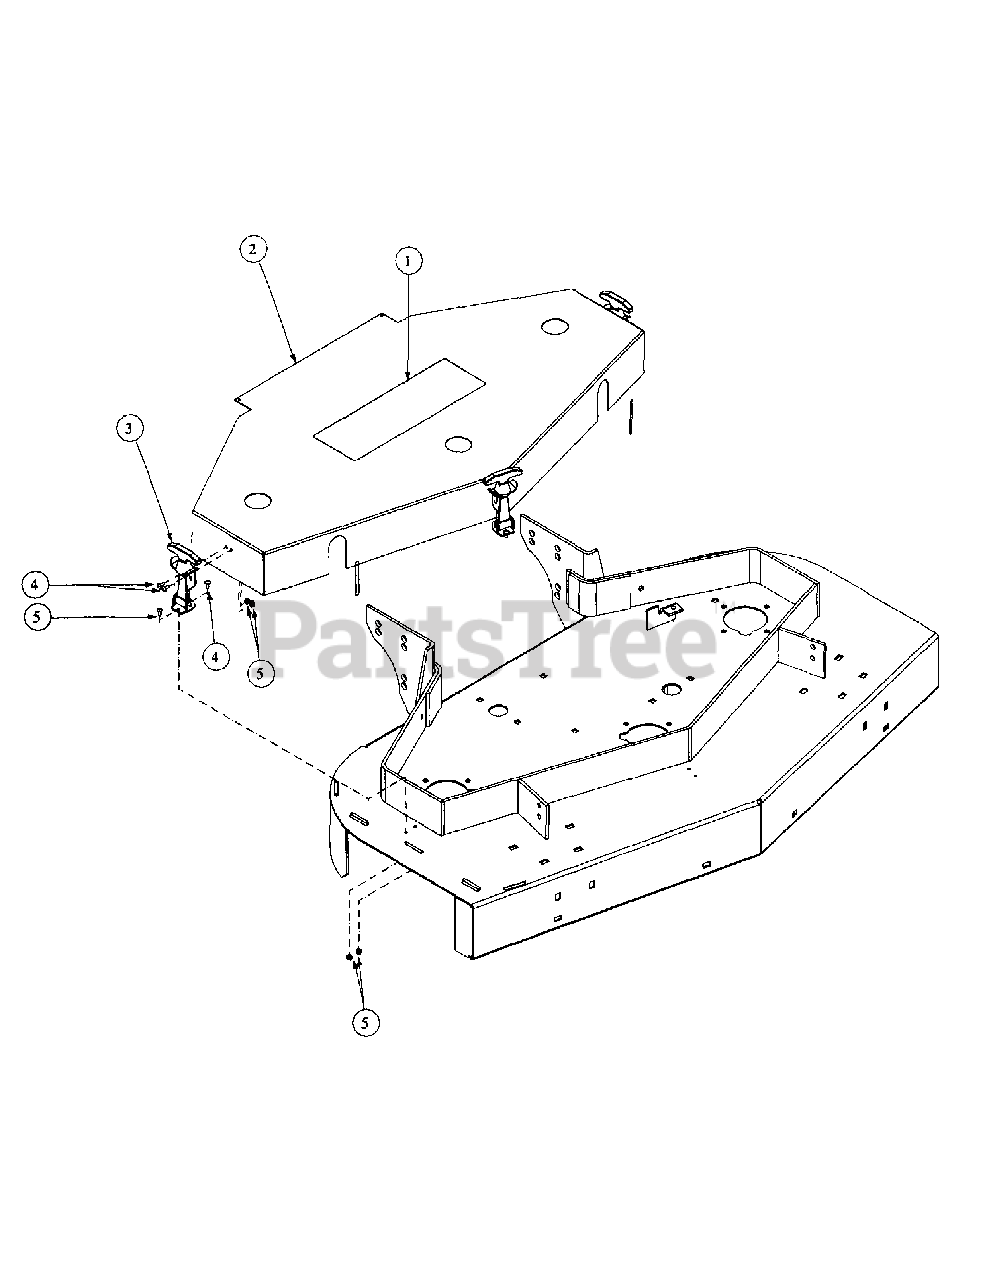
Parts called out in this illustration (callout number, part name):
1	Label MTD Pro 48
2	Deck Cover 48"
3	Rubber Latch Hood
4	Machine Screw, 10-24 x 1/2
5	Lock Nut, Nylon Insert, #10-24
